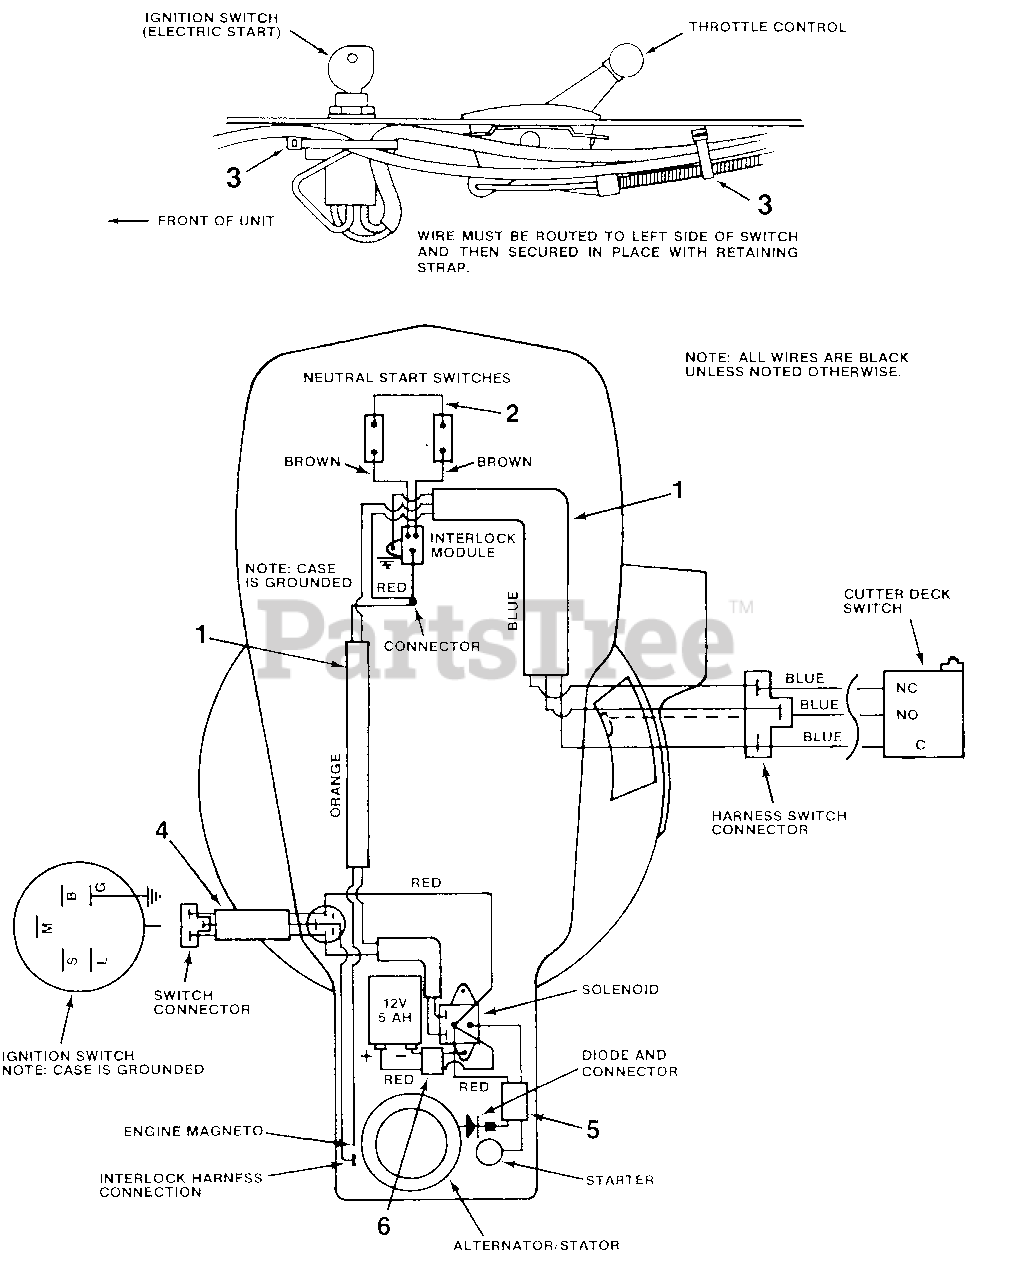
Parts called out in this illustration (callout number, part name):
1	HARNESS- Wire
2	HARNESS- Interlock
3	STRAP- Harness Retaining
4	HARNESS- Switch
5	HARNESS- Start
6	CABLE- Battery
